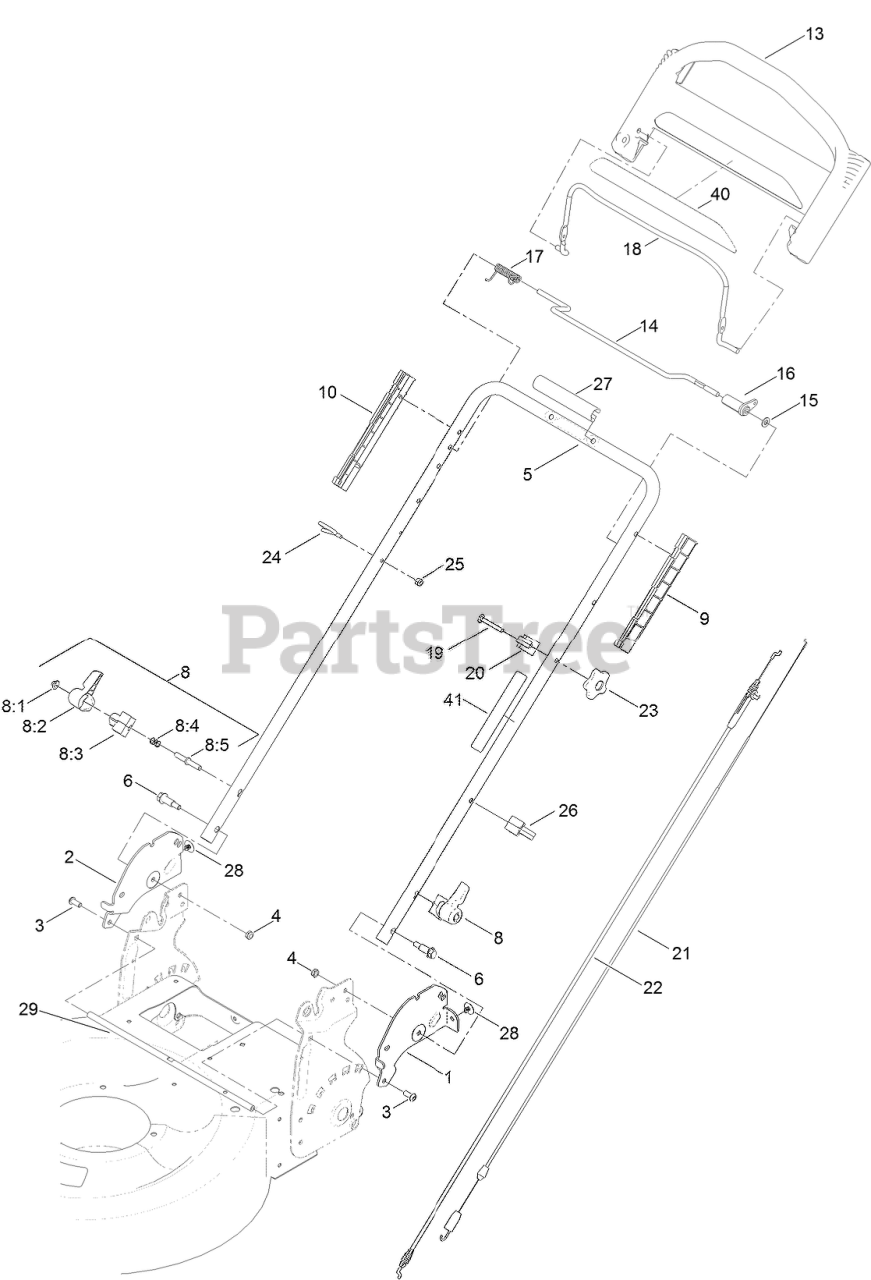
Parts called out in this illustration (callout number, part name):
1	PLATE-HANDLE, LH
2	PLATE-HANDLE, RH
3	SCREW-HSBH
4	NUT-LOCK, NI
6	BOLT-SHOULDER
8	QUICK RELEASE ASM
8:1	NUT-PUSH
8:2	LEVER
8:3	ANCHOR-SPRING
8:4	SPRING-COMPRESSION
8:5	ROD-RELEASE
9	GUIDE-LH
10	GUIDE-RH
13	HANDLE-CONTROL
14	BAR-CONTROL, TRACTION
15	WASHER-PLAIN
16	LEVER-TRACTION
17	Spring-Torsion
18	BAIL-BRAKE
19	SCREW-CARR
20	ANCHOR-CABLE
21	CABLE-TRACTION
22	CABLE-BRAKE
23	KNOB-HANDLE, LOCKING
24	GUIDE-ROPE
25	NUT-LOCK, NI
26	GUIDE-CABLE
27	HANDLE-COVER
28	CLIP-TREE
29	Rod-Stiffener
41	DECAL-TRACTION, ADJUST
